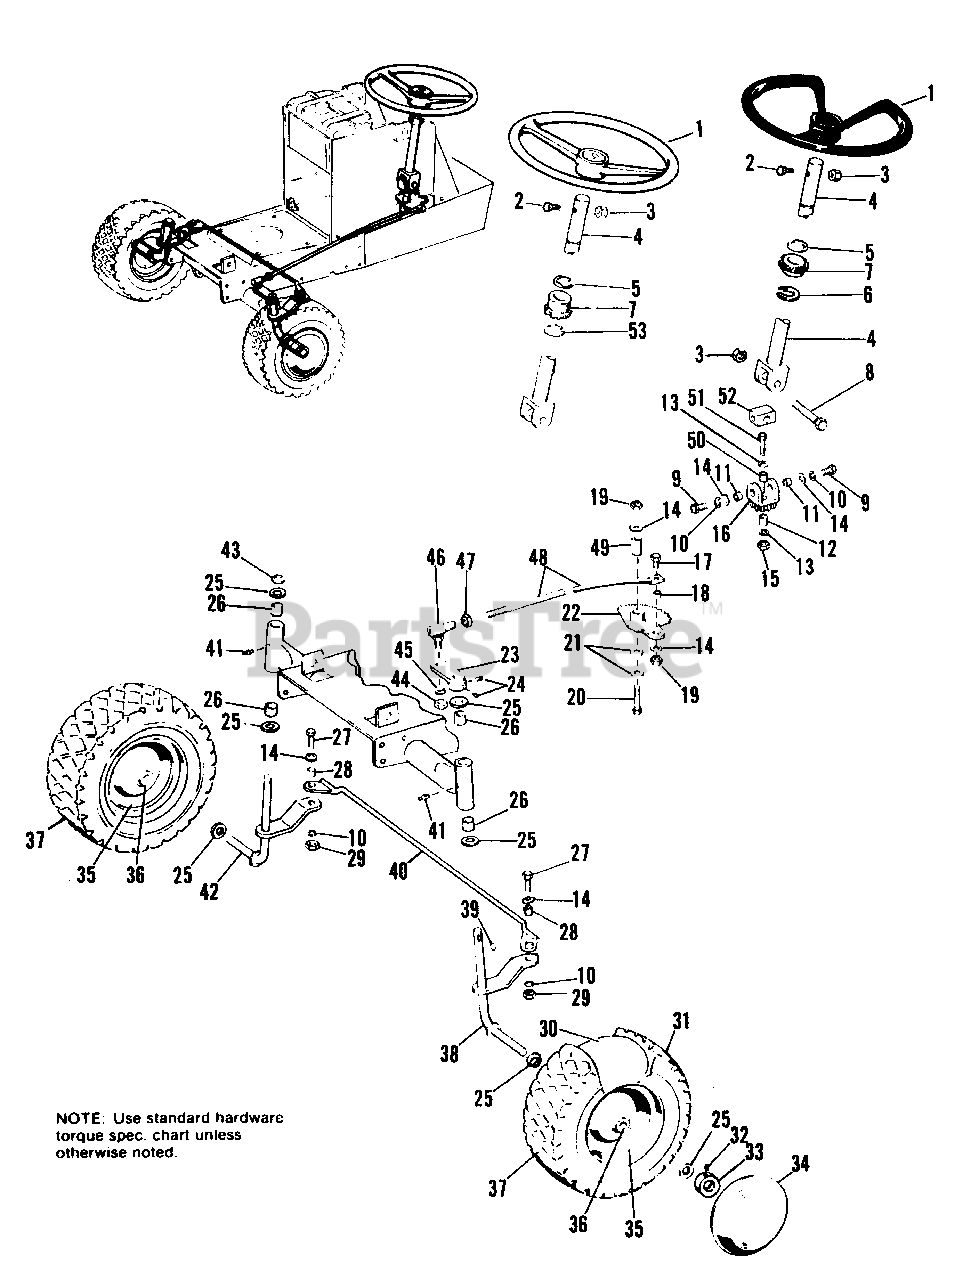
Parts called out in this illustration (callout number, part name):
1	WHEEL ASSY., Steering (990489, 1690019, 1690020 & 1690106 Only)
2	CAPSCREW, Hex Hd., 5/16-18 x 1-1/4
3	LOCKNUT, Hex, 5/16-18
4	SHAFT ASSY., Steering
5	WASHER, Nylon (1690019, 1690020 & 1690106)
6	RING, Snap
8	CAPSCREW, Hex Hd., 5/16-18 x 1-1/2
9	CAPSCREW, Hex Hd., 3/8-16 x 3/4
10	LOCKWASHER, 3/8 (Qty. 4 on 1690019, 1690020, 1690106 Only)
14	WASHER, Plain, 3/8
15	LOCKNUT, Jam, 3/8-16
16	FORK & PINION ASSY.
17	CAPSCREW, Hex Hd., 3/8-16 x 1
19	LOCKNUT, Hex, 3/8-16 (Qty. 1 on 990489, 990577, 990780 & 990904 Only)
20	CAPSCREW, Hex Hd., 3/8-16 x 2-1/2
21	WASHER
22	GEAR ASSY., Steering
23	LEVER ASSY., Steering
24	SETSCREW, 5/16-18 x 1/2
27	SCREW, Special (1690019, 1690020, 1690106 0nly)
27	CAPSCREW, Hex Hd., 3/8-16 x 1-1/4
29	NUT, Hex, Full, 3/8-16
30	LINK ASSY., Drag
32	SETSCREW, 5/16-18 x 5/16
33	COLLAR, Set
37	WHEEL & TIRE ASSY.
38	SPINDLE ASSY., L.H.
39	KEY, Hi-Pro
40	LINK ASSY., Drag (1690019, 1690020, 1690106 Only)
41	FITTING, Grease
42	SPINDLE ASSY., R.H.
43	RING, Retaining
44	NUT, Hex, Full, 1/2-20
45	LOCKWASHER, 1/2
46	JOINT, Ball
47	LOCKNUT, Jam, 1/2-20
48	ROD, Tie (1690019, 1690020, 1690106 Only)
51	CAPSCREW, Hex Hd., 3/8-16 x 1-1/2
52	PIN, Universal Joint
53	RING, Retaining (990489, 990577, 990780 & 990904 Only)
